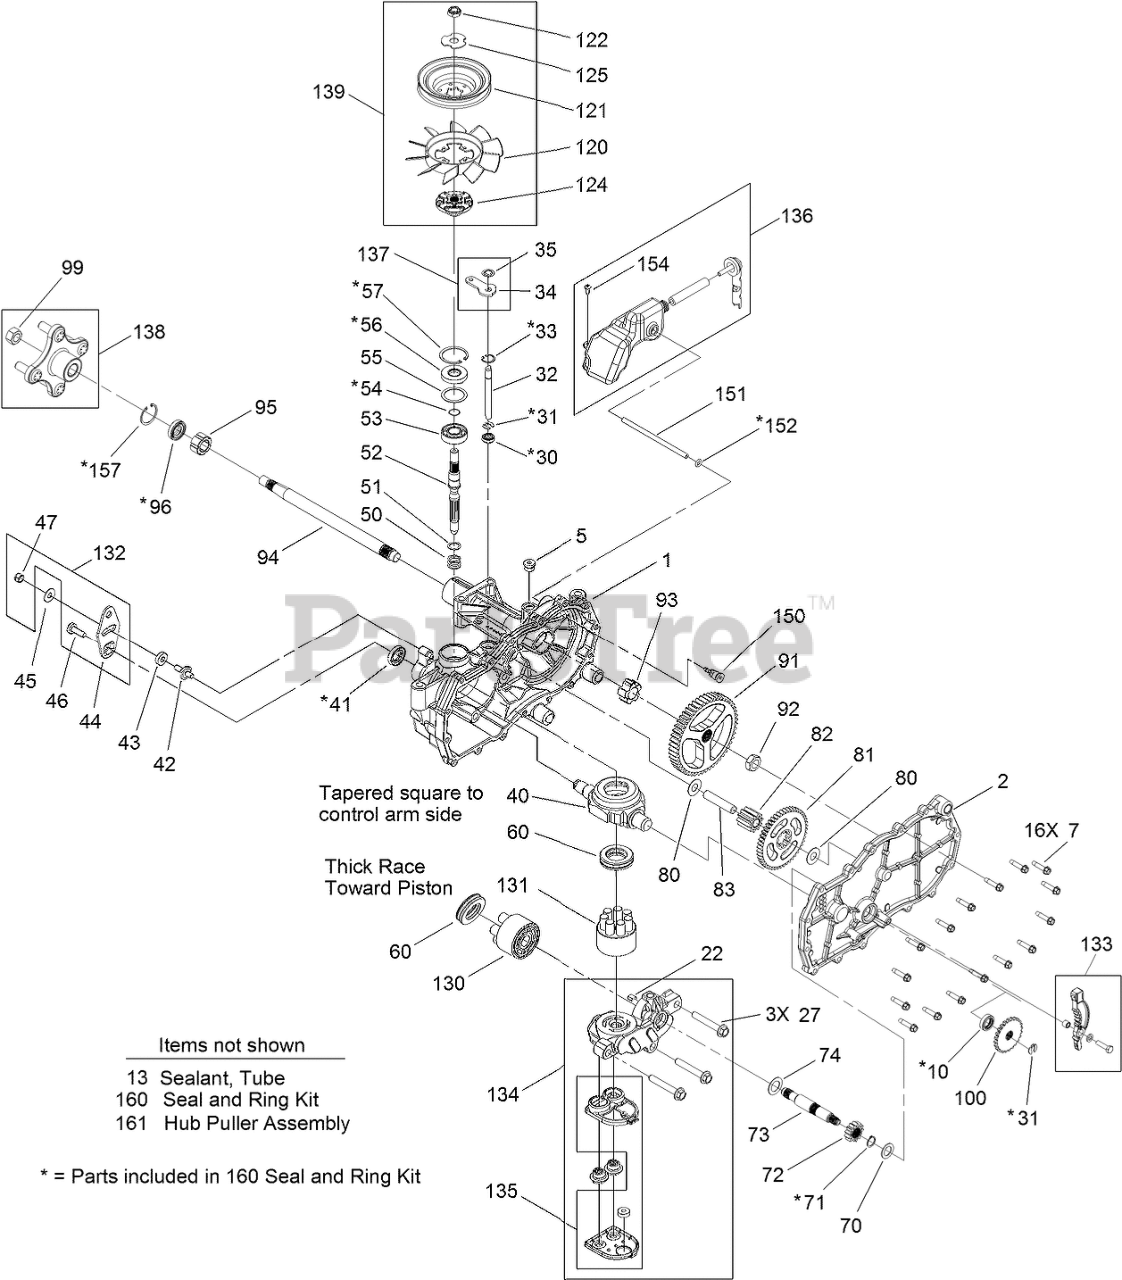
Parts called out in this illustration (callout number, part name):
1	MAIN HOUSING ASM
2	HOUSING SIDE KIT
5	PLUG-THREAD, STRAIGHT
7	SCREW-HHF
10	SEAL-LIP
22	PLATE-BYPASS
27	BOLT-HEX FLANGE
30	SEAL-LIP
31	RING-RETAINING, EXTERNAL
32	ROD-BYPASS
33	RING-RETAINING, INTERNAL
34	ARM-BYPASS
35	RING-RETAINING, EXTERNAL
40	SWASHPLATE-TRUNNION
41	SEAL-LIP
43	PUCK-FRICTION
44	ARM-CONTROL
45	WASHER
50	SPRING-COMPRESSION
51	WASHER
52	SHAFT-INPUT
53	BEARING-BALL
54	RING-RETAINING
55	SPACER
56	SEAL-LIP
57	RING-RETAINING
60	BEARING-THRUST
70	WASHER-FLAT
71	RING-RETAINING
72	GEAR-PINNION, 13T
73	SHAFT-MOTOR
74	WASHER
80	WASHER
81	GEAR-10T/48T
82	GEAR-JACKSHAFT, 10T
83	PIN-JACKSHAFT
91	GEAR-BULL
92	NUT-HJ
93	BUSHING-INBOARD
94	SHAFT-AXLE
95	BEARING-SLEEVE
96	SEAL-LIP
99	NUT-HEX LOCK
100	DISC-BRAKE, COG
120	FAN-6 INCH
121	PULLEY
122	NUT-LOCK
124	HUB
125	WASHER-SLOTTED
130	CYLINDER BLOCK KIT
131	PUMP BLOCK ASM
132	CONTROL ARM KIT
133	BRAKE ARM KIT
134	CENTER SECTION FILTER KIT
135	FILTER KIT
136	EXPANSION TANK KIT
137	BYPASS ARM KIT
138	HUB KIT
139	FAN PULLEY KIT
150	FITTING-SAE
152	O-RING
154	BOLT-SELF TAPPING
157	RING-RETAINING
